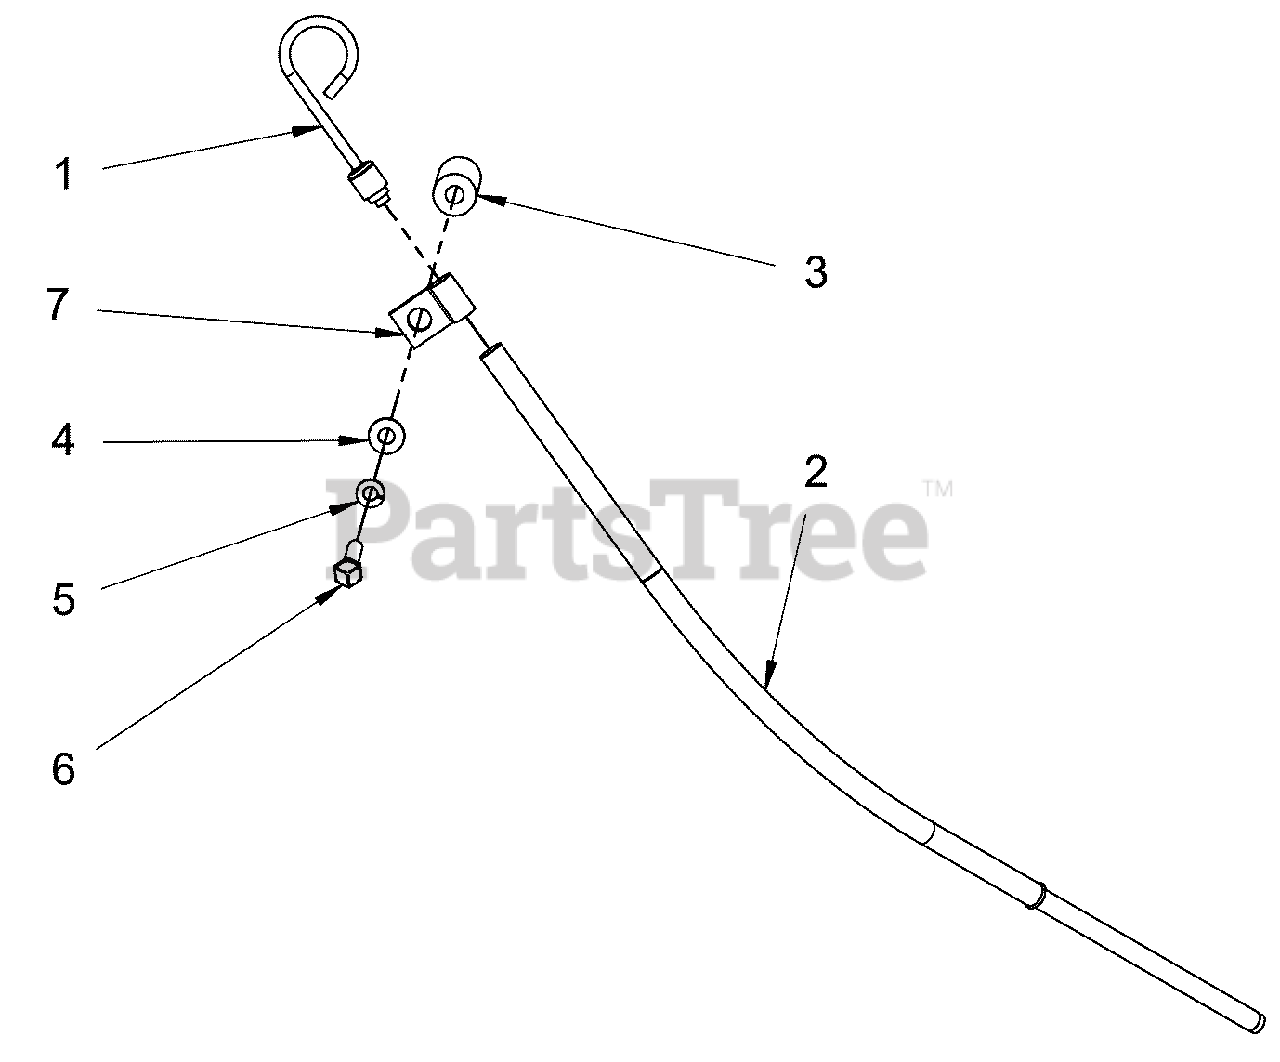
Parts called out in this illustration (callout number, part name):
3	* SPACER
4	* WASHER
5	* WASHER
6	* BOLT
7	* CLAMP
